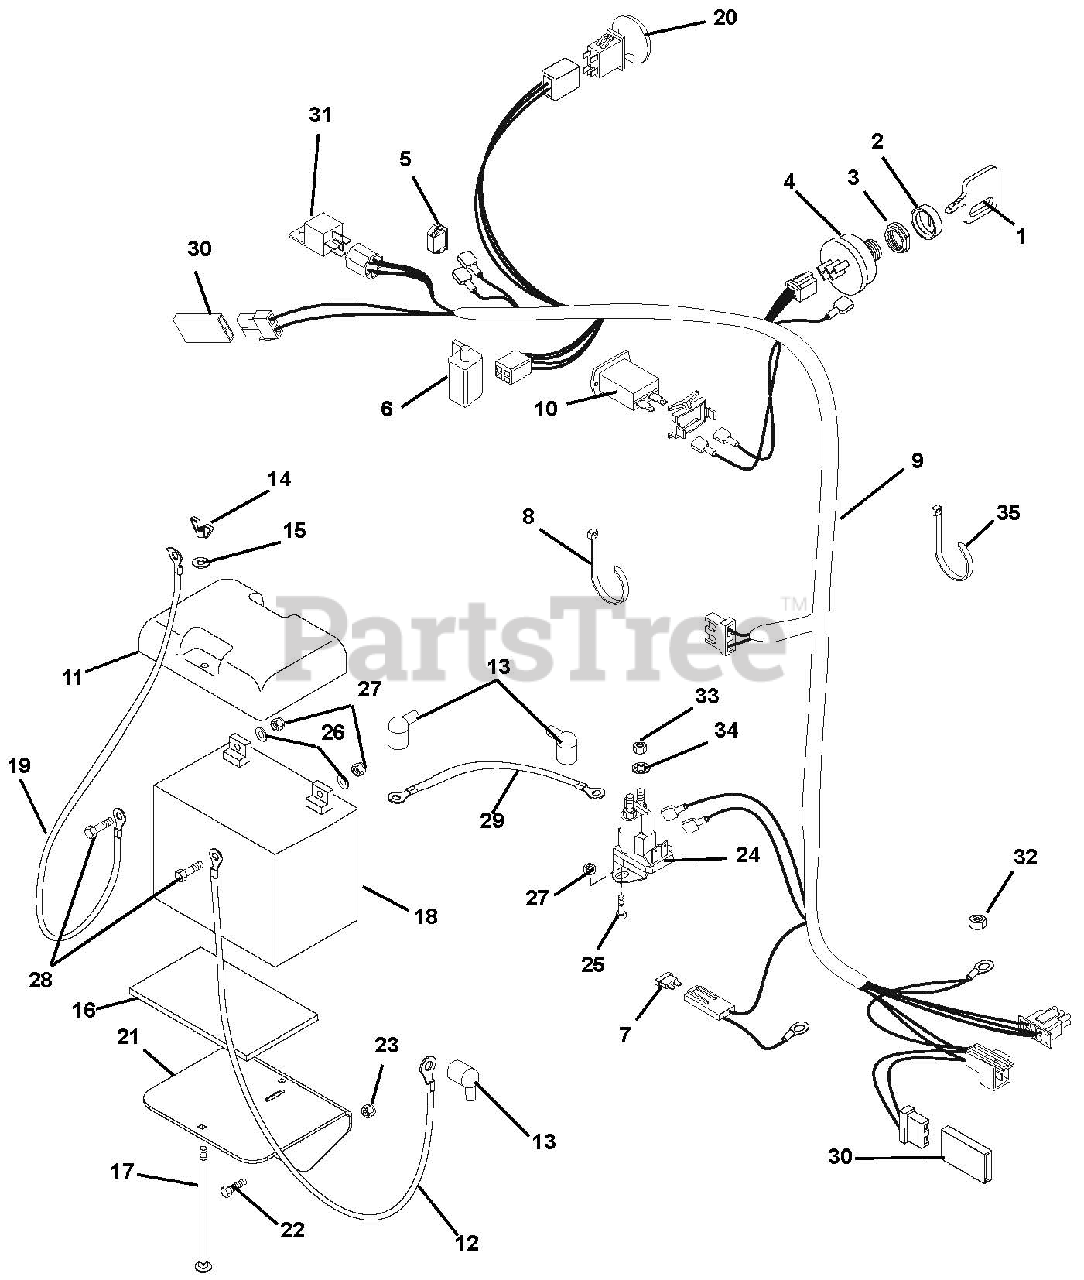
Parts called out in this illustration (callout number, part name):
1	Key- with Cap
2	Cap, Ignition Switch
3	Nut, Panel .625-32
4	Key Switch
5	Light, Indicator
6	Switch- Double Pole N.O./N.O.
7	Fuse-25 AMP
8	Tie Wrap-Black
9	Wire Harness
10	Hour Meter-Quartz
11	Cover-Battery
12	Cable, Positive Battery
13	Boot, Eyelet Terminal
14	Nut-Locking-Wing .25-20
15	Washer-Flat-Steel .281 x .625 x .065
16	Pad, Battery
17	Bolt-Round Head Square Neck .25-20 x 7.50 Grade 2
19	Cable, Negative Battery
20	Switch, Clutch With Retainer
21	Weldment, Battery Tray
22	Bolt-Hex .38-16 x 1.00 Grade 5
23	Nut-Locking-Nylon .38-16
24	Solenoid
25	Bolt-Hex .25-20 x .75 Grade 5
26	Washer-Flat-Steel .281 x .62 x .065
27	Nut-Locking-Flange .25-20
28	Bolt-Hex .25-20 x .75 Grade 5
29	Starter Cable 6.75"
30	Diode, Connector Shell
31	Relay
32	Nut-Locking-Top-Flange .31-18
33	Nut- Jam .31-24
34	Washer-Locking .31
35	Tie Wrap
